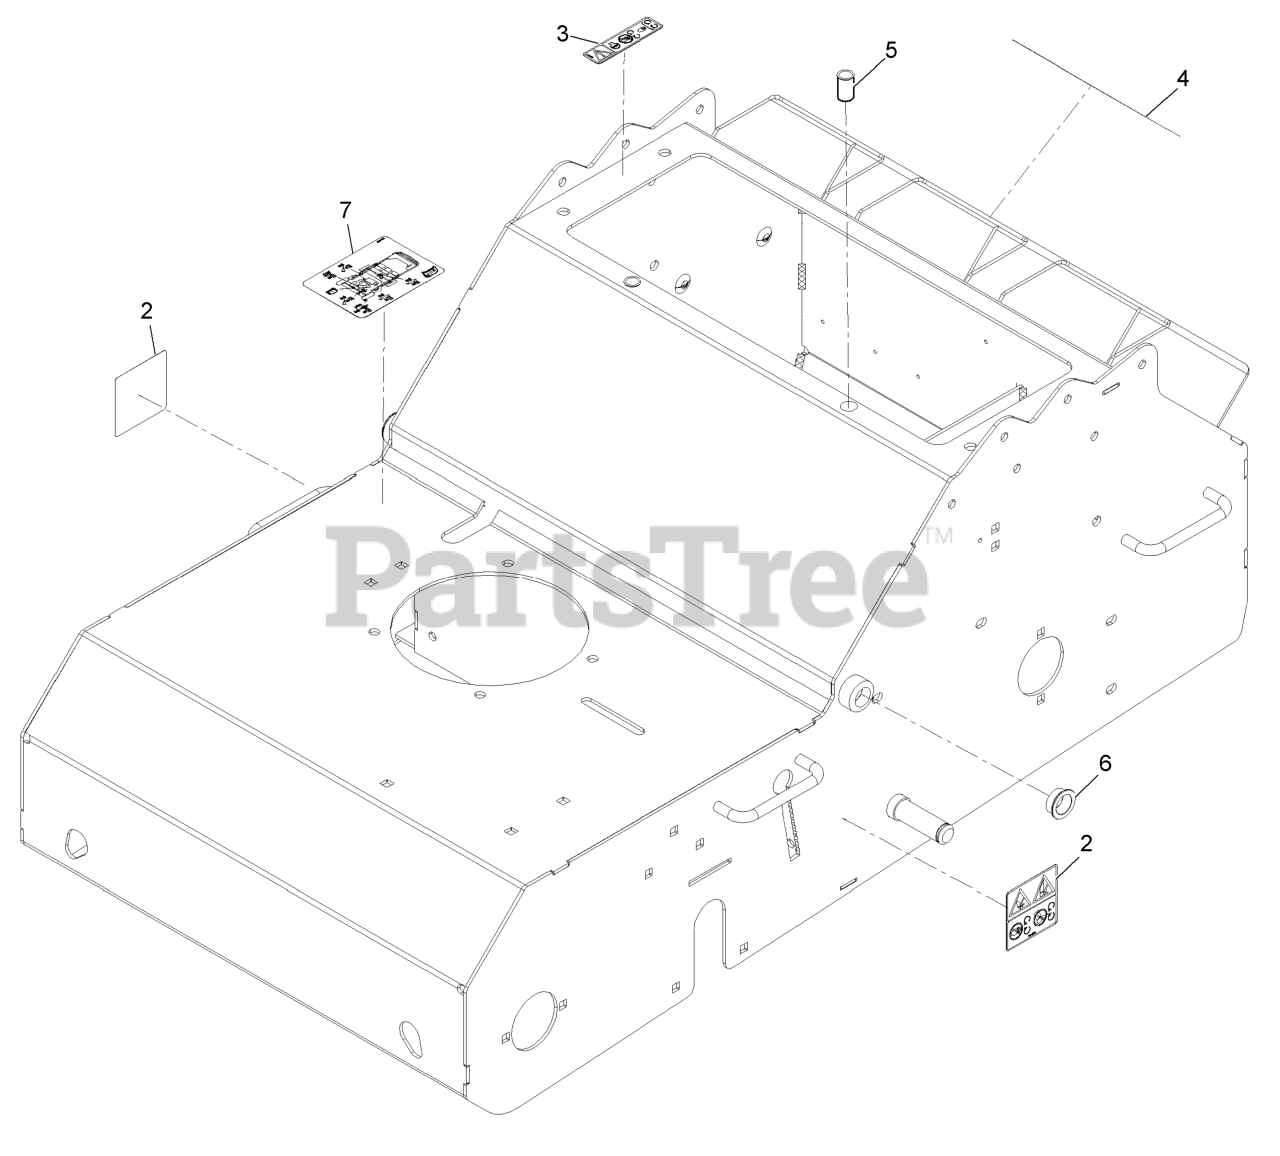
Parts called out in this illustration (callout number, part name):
2	DECAL-WARNING
3	DECAL-DANGER
4	Decal-Warning
5	NUT-CLINCH
6	BUSHING-BRONZE
7	Decal-Service Aid
